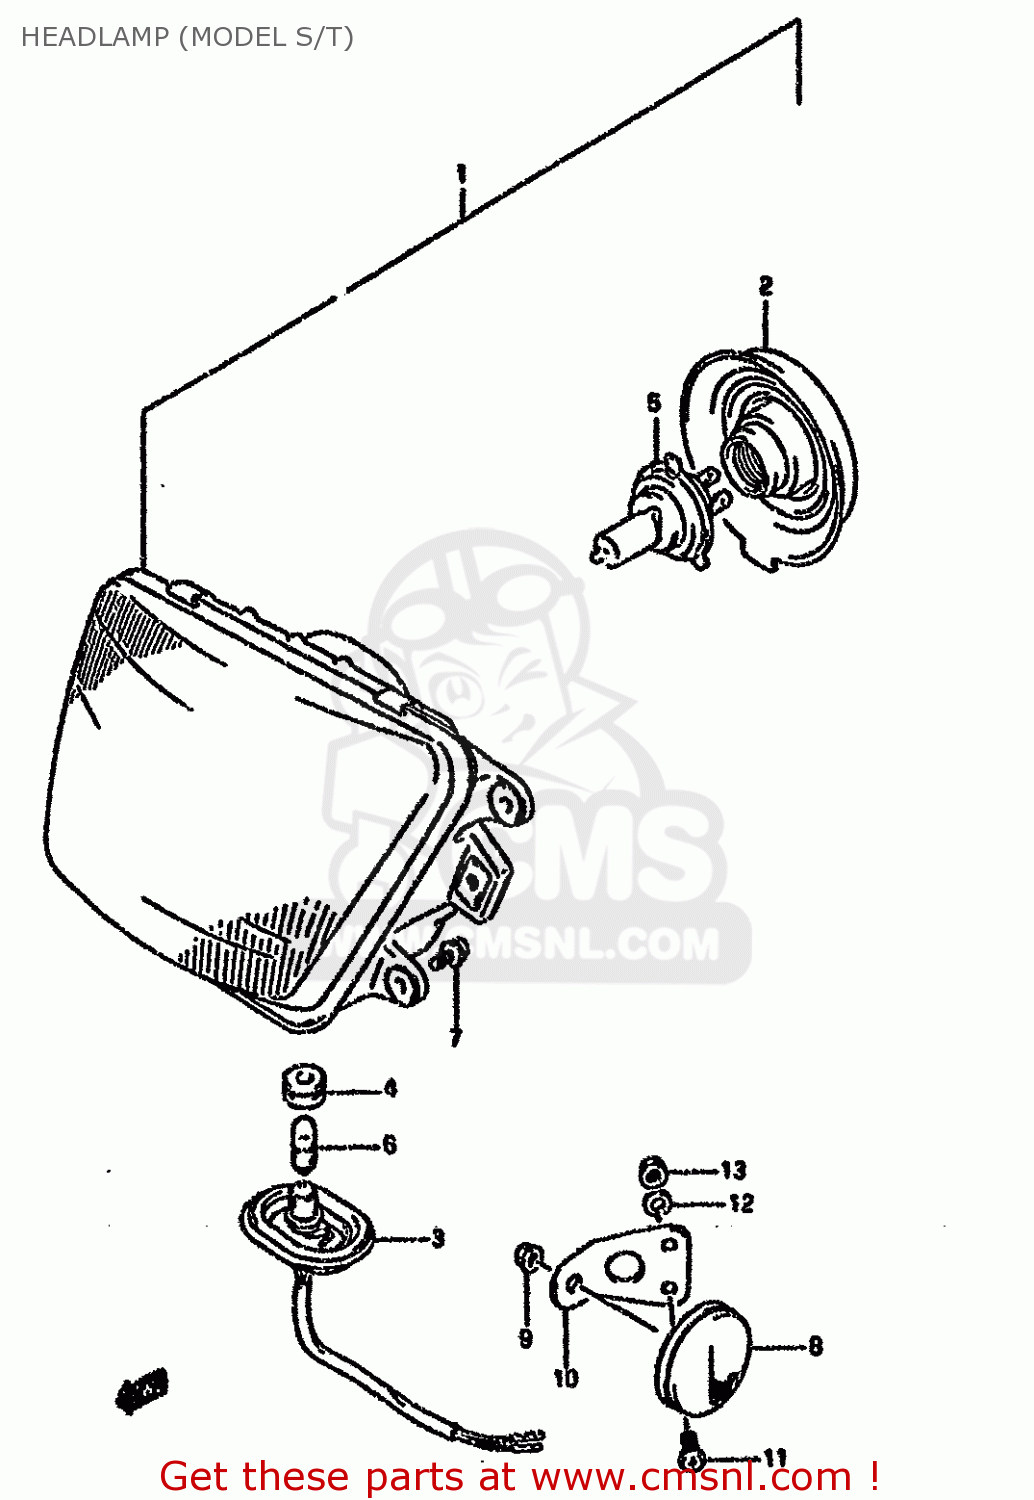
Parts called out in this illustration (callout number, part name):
1	HEADLAMP ASSY
2	COVER,SOCKET
3	SOCKET
4	JOINT,RUBBER
5	BULB(12V60/55W,H4)
6	BULB(12V4W)
7	SCREW
8	REFLECTOR,REFLEX FR
9	NUT
10	BRACKET,FRONT SIDE RH
11	SCREW
12	WASHER
13	NUT, LICENSE
